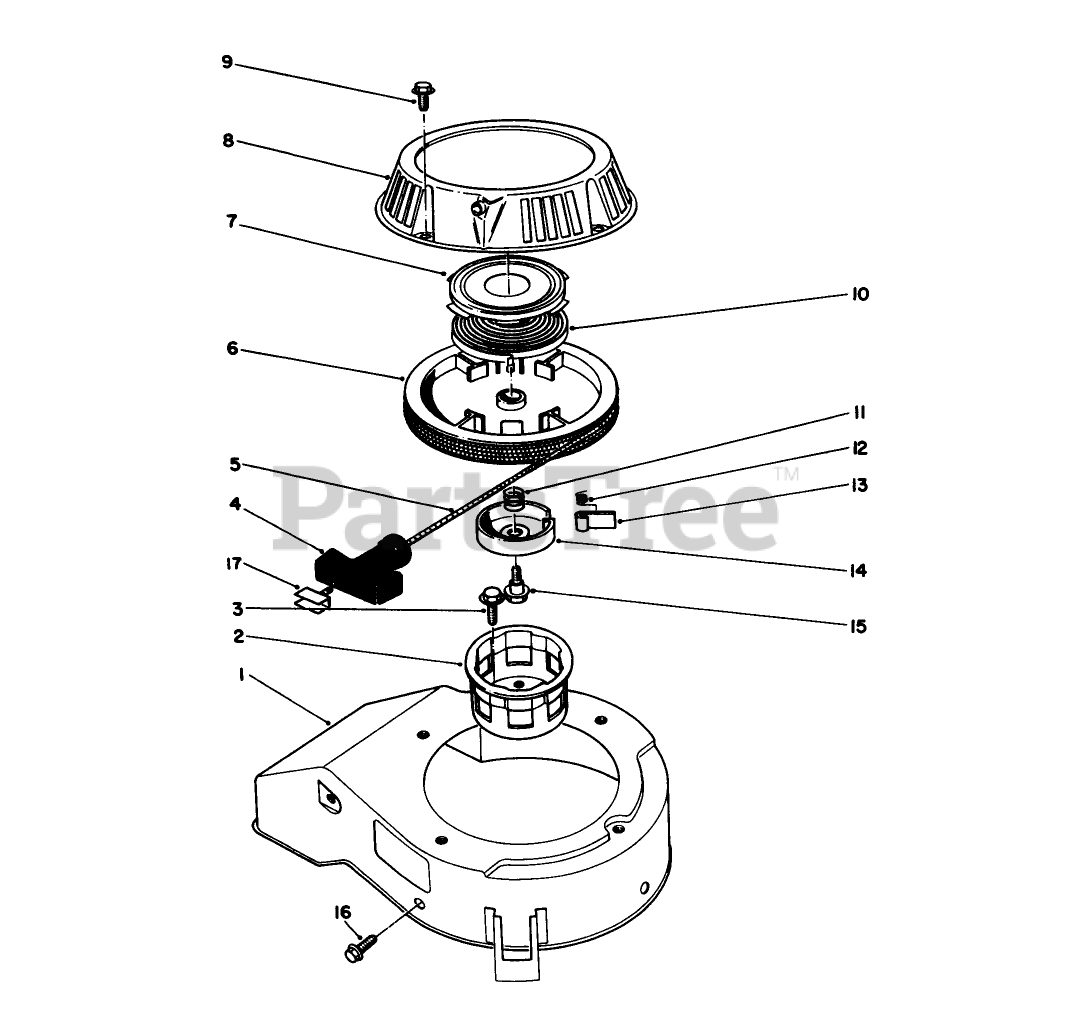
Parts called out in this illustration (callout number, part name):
1	COVER
2	CUP - STARTER
4	HANDLE-RECOIL
5	ROPE-STARTER
7	Retainer-Recoil Spring
9	SCREW-HHF
10	Spring-Recoil
11	SPRING
12	SPRING
14	RETAINER
17	Insert Handle
